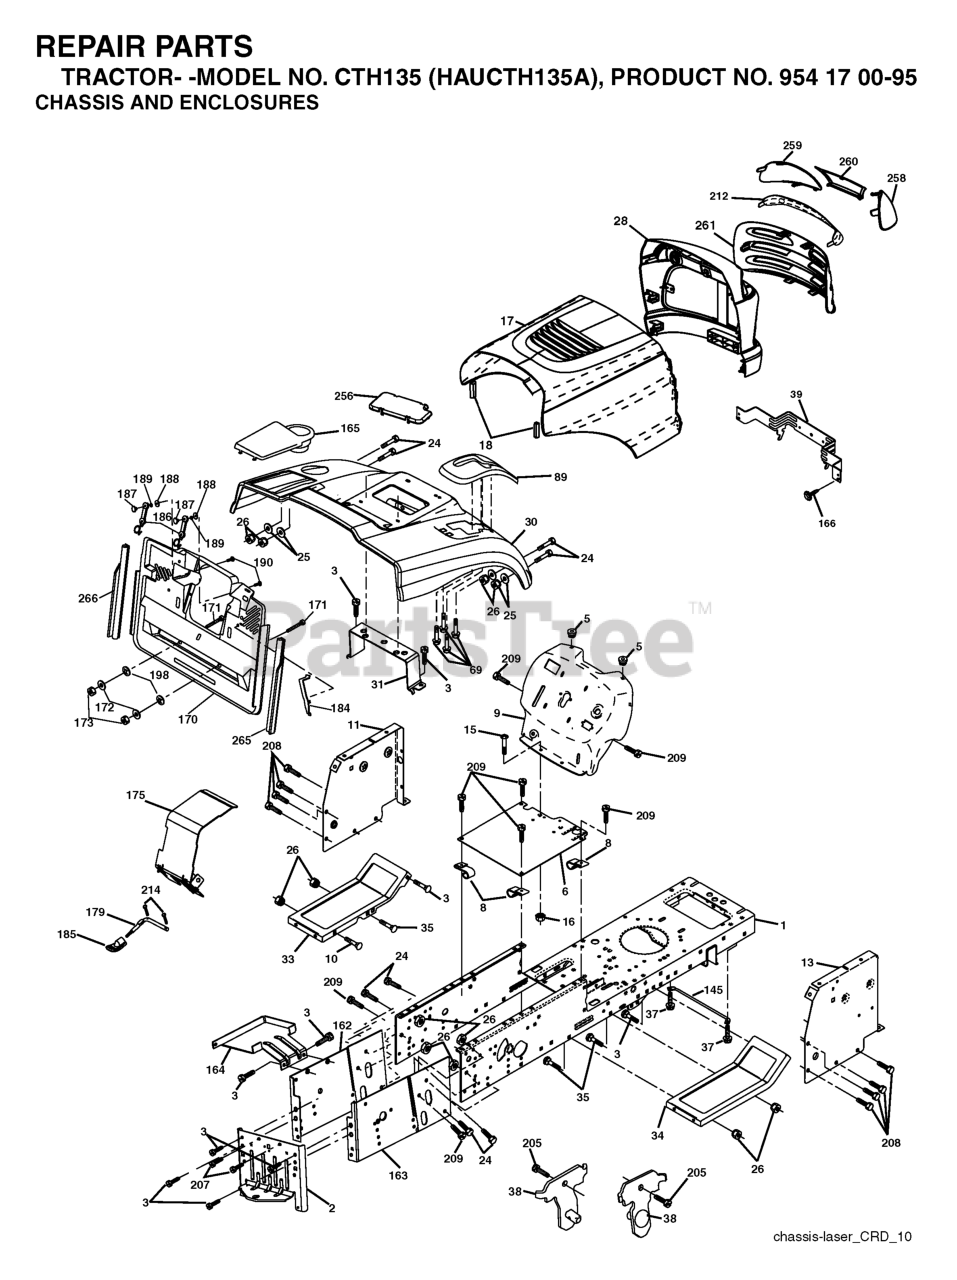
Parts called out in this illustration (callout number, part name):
2	DRAWBAR
3	SCREW 3/8-16X3/4
5	BUMPER.RUBBER.HOOD
6	PLATE
8	CLIP,INSULATOR
10	BOLT D
11	PANEL.DASH.LH.LTX
13	PANEL ASM, DASH RH
15	Screw, Machine, Truss Head 5/16-18 UNC x 3/4
16	NUT
17	HOOD
18	BUMPER.HOOD.LARGE.1.75"
25	WASHER
26	NUT
31	BRACKET SUPPORT FENDER
33	FOOTREST PNT LH
34	FOOTREST PNT RH
37	Screw 5/16-18 x 1/2 Hex, Self Tapping 5/16-18 x 1/2
38	BRACKET ASM PIVOT MOWER REAR
39	BRACKET PIVOT LASER
69	SCREW.HI-LO.CONSOLE
89	COVER.BATTERY.CRD.GREY
145	ROD PIVOT CHASSIS/HOOD
162	BRACKET
163	BRACKET EXTEN CHASSIS RH CRD
165	RP.COVER.BATTERY.CRD.GREY
166	SCREW
172	WASHER
184	BRACKET.ACTUATOR.BAGGER.SRD
186	LATCH ASSY
187	WELDNUT
189	LOCKWASHER #10
190	SCREW
207	SCREW, 5/16-18 X 1/2
208	SCREW 3/8-16X1/2
209	SCREW, 3/8-16X3/4
212	INSERT.LENS.REFLECTIVE
214	RETAINER M
256	COVER FENDER CRD
258	LENS LH
259	LENS LH
260	COVER.LENS.HUSQ.LASER
265	SEALING
266	SEALING
